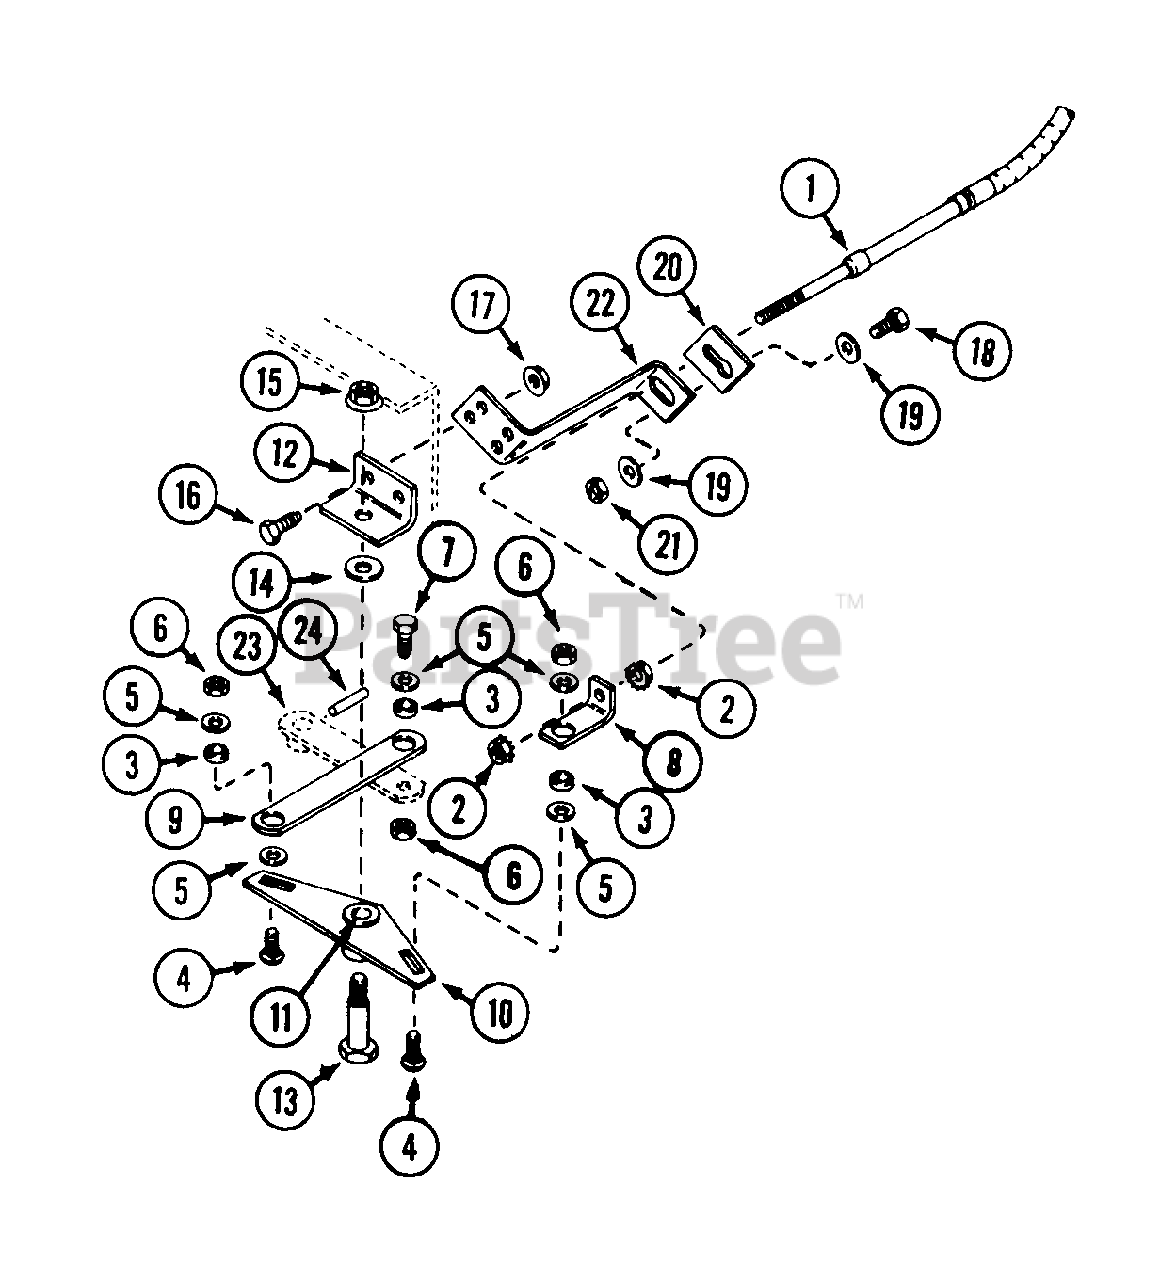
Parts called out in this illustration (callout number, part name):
1	CABLE - steering
2	NUT - #10 - 32
3	BUSHING - steering cable
4	BOLT - 1/4" - 20 x 1" carriage
5	WASHER - 1/4"
6	NUT - 1/4" - 20
7	BOLT - 1/4" - 20 x 1"
8	BRACKET - steering cable end
9	LINK - control cable
12	BRACKET - bellcrank mounting
13	BOLT - shoulder
14	WASHER - 1/2"
15	NUT - 3/8" - 16 flange lock
16	BOLT - 5/16" - 18 x 1"
17	NUT - 5/16" - 18
18	BOLT - 1/4" - 20 x 1"
19	WASHER - 1/4"
20	PLATE - cable mounting
21	NUT - 1/4" - 20 lock
22	BRACKET - cable mounting
23	ARM - transmission
